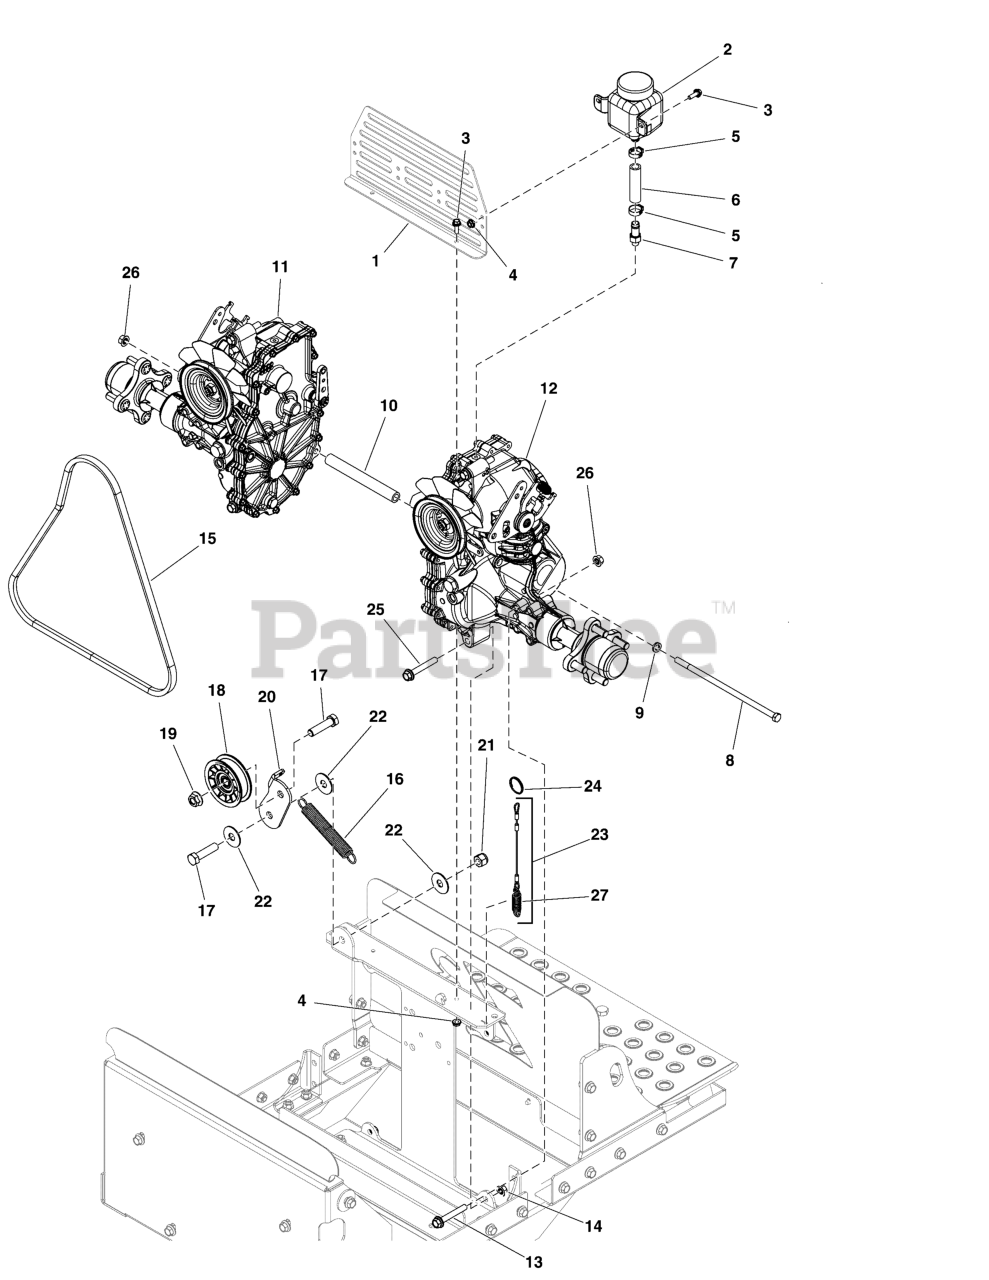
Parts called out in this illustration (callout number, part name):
1	Refer to: CE Guarding Group
2	RESERVOIR, HYDRO OIL, 350 ML
3	BOLT, 1/4-20 X 3/4, FLANGE, CZ
4	NUT, 1/4-20 HEX SERR. FLANGE
5	CLAMP, HOSE, .75 FREE DIA.
6	HOSE, 1/2" PUSH-ON, 2.75"
7	FITTING, STRAIGHT 7/16-20 UNF
8	BOLT, HEX, 3/8-16 X 10" GD 5, CZ
9	WASHER, 3/8 SAE
10	SPACER, .75 OD X 6.40 LONG, 10GA
11	TRANSAXLE, ZT3100, RH, ZJ-LPRP-3A7C-19XX
11	TRANSAXLE, ZT-3100, RH,ZJ-LPRP-SA7C-19XX
12	TRANSAXLE, ZT3100, LH, ZJ-HPRP-3A7B-19XX
12	TRANSAXLE, ZT-3100, LH,ZJ-HPRP-SA7B-19XX
13	BOLT, HEX, 3/8-16 X 3", SER FLG GRD5, CZ
14	NUT, 3/8-16, FLANGE, SERRATED UNDER HEAD
15	BELT, DRIVE, Z3000
16	SPRING, IDLER, #98
17	BOLT, 1/2-13 X 2" GD5 CZ
18	PULLEY IDLER 3.0 OD .506ID .75
19	NUT, Hex Flange, Nylock, 1/2-13
20	IDLER ARM - BLK
21	NUT, 1/2-13 HEX NYLON LOCK
22	WASHER, 0.54 X 1.50 X 0.060, CZ
23	CABLE, HYDRO NEUTRAL RLS
24	KEY RING, SPLIT 1"
25	BOLT, 3/8-16 X 2-1/2, FLANGE, CZ
26	NUT, 3/8 - 16 HEX NYLOCK FLANGE
27	SPRING, EXTENSION, #29
